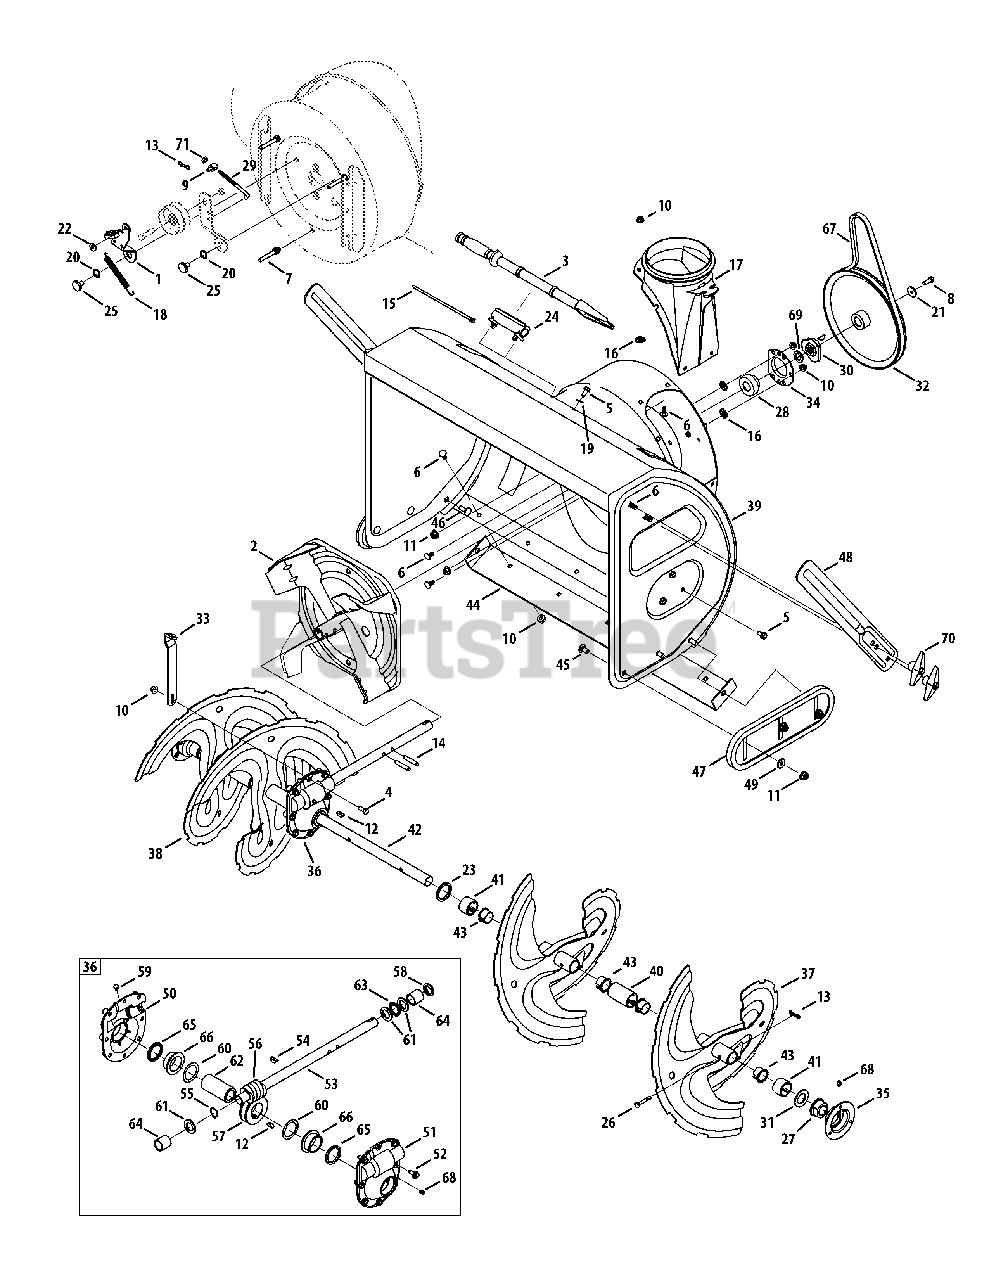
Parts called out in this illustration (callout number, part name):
1	Bracket Assy, Auger Brake
2	Impellar, 16"
3	Tool, Cleanout
4	Scr,Hex Cap, 5/16-18 x 1.00
5	Screw, 5/16-18 x .750
6	Screw, Carriage, 5/16-18 x .75
7	Screw, 5/16-18 x .4300
8	Screw, 5/16-24 x .875
9	Ferrule
10	Nut, Flnge Lk, 5/16-18
11	Nut, Flg Lk, 3/8-16
12	Key, Woodruff,1/4 x 3/4
13	Pin, Bowtie Cotter
14	Pin, Spirol, 5/16 x 1.75
15	Tie, Cable
16	Nut, Push
17	Adapter, Chute, 6"
18	Spring, Extension
19	Washer, .349 x .879 x .063
20	Washer, .625 x .885 x .015
21	Washer, Flat, .34 x 1.50 x .150
22	Washer, .344 x .75 x .12
23	Washer, 1.01 x 1.86 x .06
24	Clip, Mounting
25	Screw, Shoulder, .625 x .17
26	Pin, Shear, .25 x 1.75
27	Bearing, Flange w/Flats
28	Bearing, Self Aligning
29	Rod, Auger Idler
30	Pulley, Adapter, .75 Dia.
31	Spacer, 1.004 x 1.375 x .25
32	Pulley, Auger Drive, 10.0
33	Bracket, Gear Box Support
34	Housing, Bearing
35	Housing, Bearing
36	Gear Box Assembly, Auger
37	Spiral Assy, LH
38	Spiral Assy, RH
39	Housing, Auger - 33"
40	Spacer, 1.0 x 1.5 x 2
41	Spacer, 1.0 x 1.5 x 1
42	Axle, Spiral, 33"
43	Bushing, Flange, 1.051 x 1.16
44	Shave Plate
45	Bolt, Carriage, 3/8-16 x 1.0
46	Bolt, Carriage, 3/8-16 x 1.25
47	Shoe, Skid
48	Drift Cutter
49	Washer, Flat, .385 x .870
50	Hsg Assy Auger RH (Inc. 65 & 66)
51	Hsg Assy Auger LH (Inc. 65 & 66)
52	Screw, LD, 5/16-18 x .750
53	Shf, Drive, Auger
54	Key, Hi Pro, 3/16 x 3/4
55	Ext, Ret, Ring
56	Gear, Worm, Dbl Thread
57	Gear, Worm, LH
58	Seal, Oil
60	Washer, Flat, 1.52 ID x 2.0 OD
61	Washer, Flat, .88 ID x .38 OD
62	Shf, Gear, Worm
63	Brg, Thrust
64	Sleeve
65	Oil Seal
66	Flange Bearing
67	V Belt,4L x 44.60 Lg.
68	Lube Fitting, 3/16 #70
69	Washer, Flat, .78 x 1.49 x .08
70	Wing Knob
71	Jam Nut, 5/16-18
